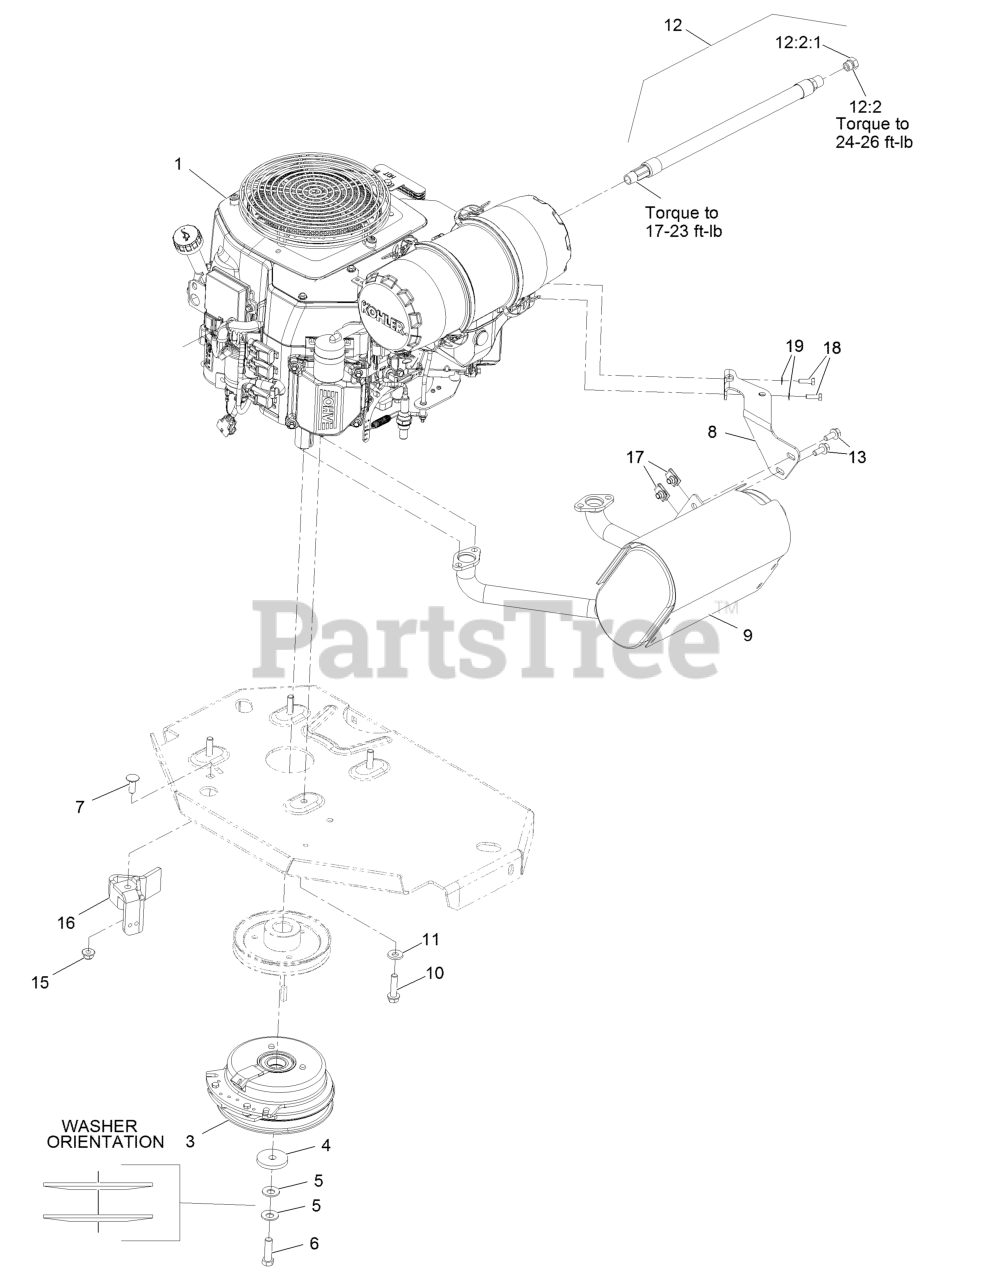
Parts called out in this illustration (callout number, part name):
1	Engine-Kohler, Pcv740 Efi LP
3	CLUTCH KIT
4	WASHER-CLUTCH
5	WASHER-SPRING
6	SCREW-HH 7/16-20 X 1 1/2 W/LOCTITE
7	SCREW-CARR
8	MUFFLER BRACKET KIT
10	SCREW-HWH
11	WASHER-BELLEVILLE
12	OIL DRAIN HOSE ASM
12:2	PLUG-HH
12:2:1	O-RING
13	SCREW-HHF
15	NUT-HF, NI
16	CLUTCH-ANCHOR
18	SCREW-HH M6-1 X 20Mm W/Patch
19	WASHER-SPRING
